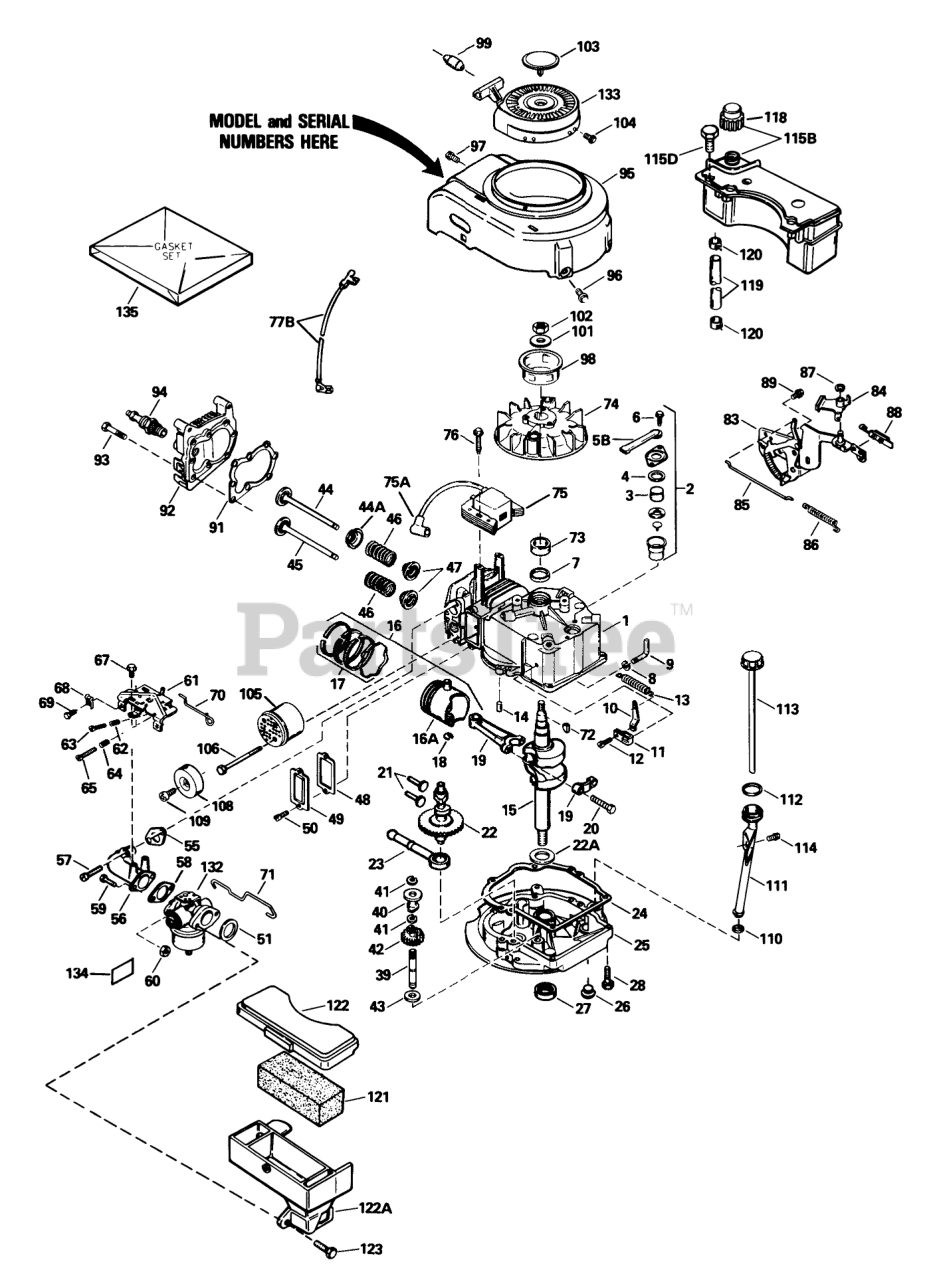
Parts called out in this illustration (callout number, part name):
1	Cylinder Assembly (Incl. Ref. #7 & 14)
2	Breather Assembly (Incl. Ref. #3-6)
3	Element-Breather
4	Gasket-Breather
5B	Tube, Breaker
6	Screw (10-24 x 9/16)
7	Seal-Oil
8	Washer-Flat
9	Rod-Governor (Incl. Ref. #8)
10	Governor Lever
11	Clamp-Lever, Governor
12	Screw
13	Spring Governor
14	Pin-Dowel
15	Crankshaft
16	Piston-Pin & Ring Assy. (Std.) (Incl. Ref. #16A, 17 & 18)
16	Piston-Pin & Ring Assembly (.010 oversize) (Incl. Ref. #16A, 17 & 18)
16	Piston-Pin & Ring Assembly (.020 oversize) (Incl. Ref. #16A, 17 & 18)
16A	Piston & Pin Assembly (Std.) (Incl. Ref. #18)
16A	Piston & Pin Assembly (.010 oversize) (Incl. Ref. #18)
16A	Piston & Pin Assembly (.020 oversize) (Incl. Ref. #18)
17	Ring Set-Piston (Std.)
17	Ring Set, Piston(.0100versize)
17	Ring Set (.020" OS)
18	Ring-Retaining, Piston Pin
19	Rod Assembly-Connecting (Incl. Ref. #20)
20	Bolt-Rod, Connecting
21	Lifter-Valve
22	Camshaft(Mech.Comp. Release)
22A	Washer-Thrust
23	Oil Pump ASM
24	Gasket
25	Flange-Mounting (Incl. Ref. #26, 27 & 39)
26	Plug Oil Drain
27	Seal-Oil
28	Screw (1/4-20 x 1-1/4)
39	Shaft-Governor
40	Spool-Governor
41	Ring-Retaining
42	Gear Assembly-Governor (Incl. Ref. #43)
43	Washer
44	Valve-Intake (Std.) (Incl. Ref. #47)
44	Valve-Intake (1 /32" oversize) (Incl. Ref. #47)
44A	Seal Assy., Intake
45	Valve-Exhaust (Std.) (Incl. Ref. #47)
45	Valve-Exhaust (1/32" oversize) (Incl. Ref. #47)
46	Spring-Valve
47	Cap-Valve, Spring
48	Gasket-Cover, Valve
49	Cover-Valve
51	Gasket-Cleaner, Air
55	Gasket-Intake Pipe
56	Pipe-Intake (Incl. Ref. #55)
57	Screw (1/4-20 x 1)
59	Screw (1/4-28 x 7/8)
60	Nut and Lock Washer (1/4-28)
61	Bracket Assembly-Control (Incl. Ref. #62-65)
62	61709/GIL1515A/95-5
63	Screw
64	Spring-Compression
65	Screw
67	Screw (10-24 x 9/16)
68	Conduit
69	Screw (10-32 x 3/8)
70	2035A67 ADD.ASSEMBL
71	Link-Throttle
72	Key-Flywheel
74	Flywheel
75	Solid State
75A	Cover-Spark Plug
76	Screw
77B	Ground Wire
83	Bracket-S.E. Brake
84	Lever-Brake
85	Link-Control
86	Spring-Extension
87	Ring-Retaining
88	Terminal
89	Screw (1/4-20 x 3/8)
91	Gasket-Cylinder Head
92	Head-Cylinder
93	Screw (5/16-18x1-1/2)
94	Spark Plug-Resistor (R J19 L M)
95	Housing-Blower
96	Screw (1/4-20 x 1/2)
97	Screw (10-24 x 9/16)
98	Hub-Starter
99	Retainer-Starter Rope
101	Washer-Belleville
102	Nut-Flywheel
103	Plug Starter
104	Screw, Hex Hd.
105	Muffler Assembly (Incl. Ref. #106)
108	Cover-Muffler
109	Screw (8-32 x 3/8)
111	Oil Fill Tube
113	Dipstick
114	Screw (10-32 x 1/2)
115B	Tank Assembly (Incl. Ref. #118 & 120)
115D	Screw (10-32 x 35/64)
118	Cap-Fuel
119	Line-Fuel
120	Clamp-Line, Fuel
121	Filter-Air Cleaner
122	Cover-Air Cleaner
122A	Body Air cleaner
132	Carburetor (Incl. Ref. #58)
133	Starter-Rewind
134	Decal-Primer
135	Gasket Set (Incl. Items Marked)
